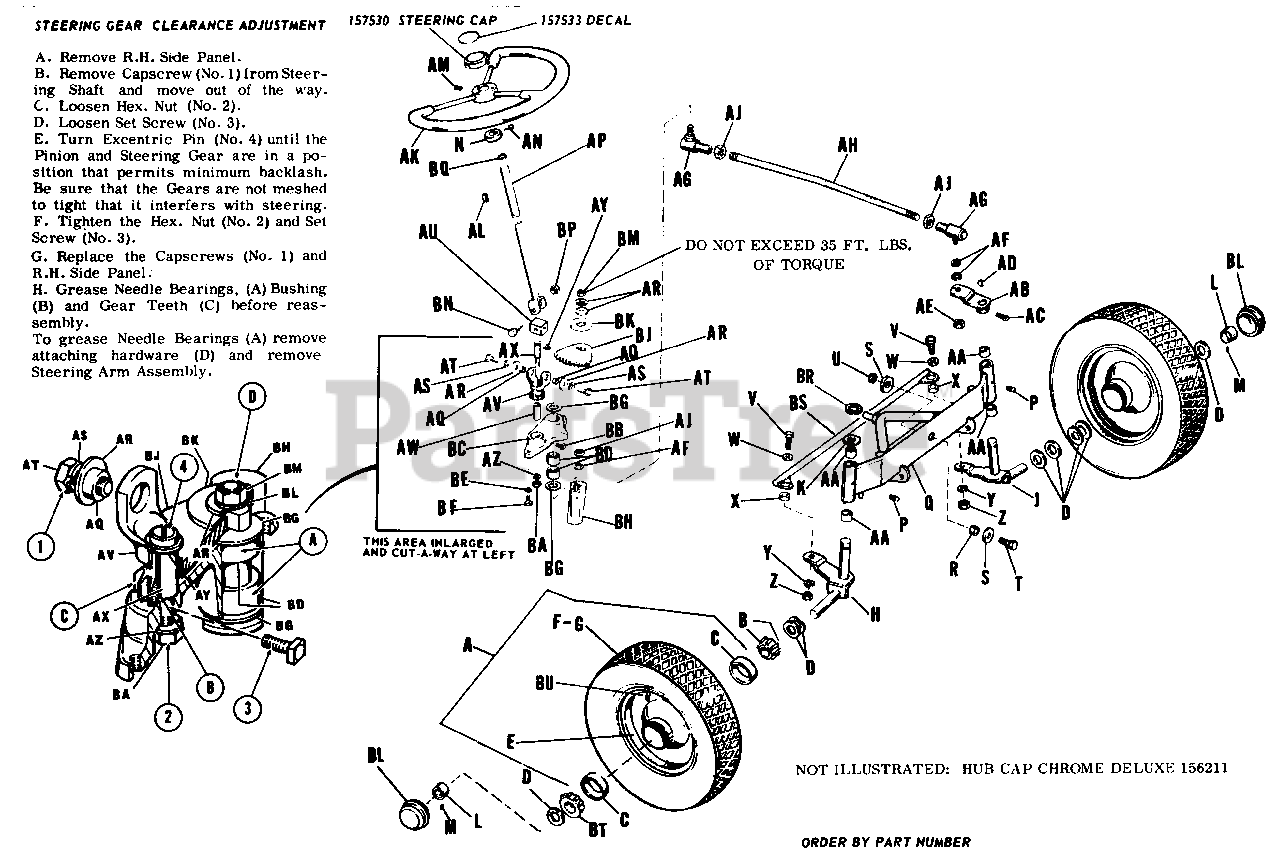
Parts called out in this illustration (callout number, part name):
A	Wheel and Tire Assembly (157505 for 2012)
B	Bearing Cone, w/seal
C	Bearing Cup
E	Wheel w/Bearing Cup
F	Tire, 4.80/4.00
G	Tube, 4.00-8
H	Spindle Assembly, R.H.
J	Spindle Assembly, L.H.
L	Set Collar
M	Cup Point Socket Head Set Screw, 5/16"-18 x 5/16" lg.
N	Set Collar
P	Grease Fitting
Q	Axle Assembly, Front
S	Plain Washer, 1/2"
T	Hex. Cap Screw, 1/2"-13 x 1" lg.
U	Full Lock Hex. Nut. 1/2"-13
V	Hex. Cap Screw, 3/8"-16 x 1-1/4" lg.
W	Plain Washer, 3/8"
Y	Lock Washer, 3/8"
Z	Full Hex. Nut, 3/8"-16
AB	Arm Assembly, Steering, L.H.
AC	Screw, Set, Cup Point, Square Head, 5/16"-18 x 1/2" lg.
AE	Full Hex. Nut, 1/2"-20
AF	Lock Washer, 1/2 "
AG	Ball Joint
AJ	Nut, 1/2"-20 N.F
AK	Steering Wheel
AL	Woodruff Key, #9
AM	Socket Head Cup Point Set Screws, 5/16"-18 x 5/16" lg.
AN	Socket Hd. Set Screw, 5/16"-18 x 1/4" lg.
AP	Steering Shaft Assembly
AR	Plain Washer, 3/8"
AS	Lock Washer, 3/8"
AT	Hex Cap Screw, 3/8"-16 x 3/4" lg.
AU	Universal Joint Pin
AV	Bushing Assembly
AX	Pin Eccentric
AY	Retainer Ring
AZ	Lock Washer
BA	Full Hex. Nut, 3/8"-16
BB	Sq. Hd. Set Screw, 1/4"-20 x.3/4" lg.
BC	Steering Bracket
BD	Needle Bearing
BE	Lock Washer, 5/16"
BF	Hex. Cap Screw, 5/16"-18 x 5/8"
BH	Steering Arm Assembly
BJ	Gear Steering
BK	Arbor Washer
BL	Hub Cap
BM	Gripco Center Lock 7/16"-14
BN	Hex CapScrew
BP	Full Hex. Nut, 5/16"-18
BQ	Snap Ring
BR	Retaining Ring
BS	Drag Link
BT	Outside Bearing
BU	Valve Stem
